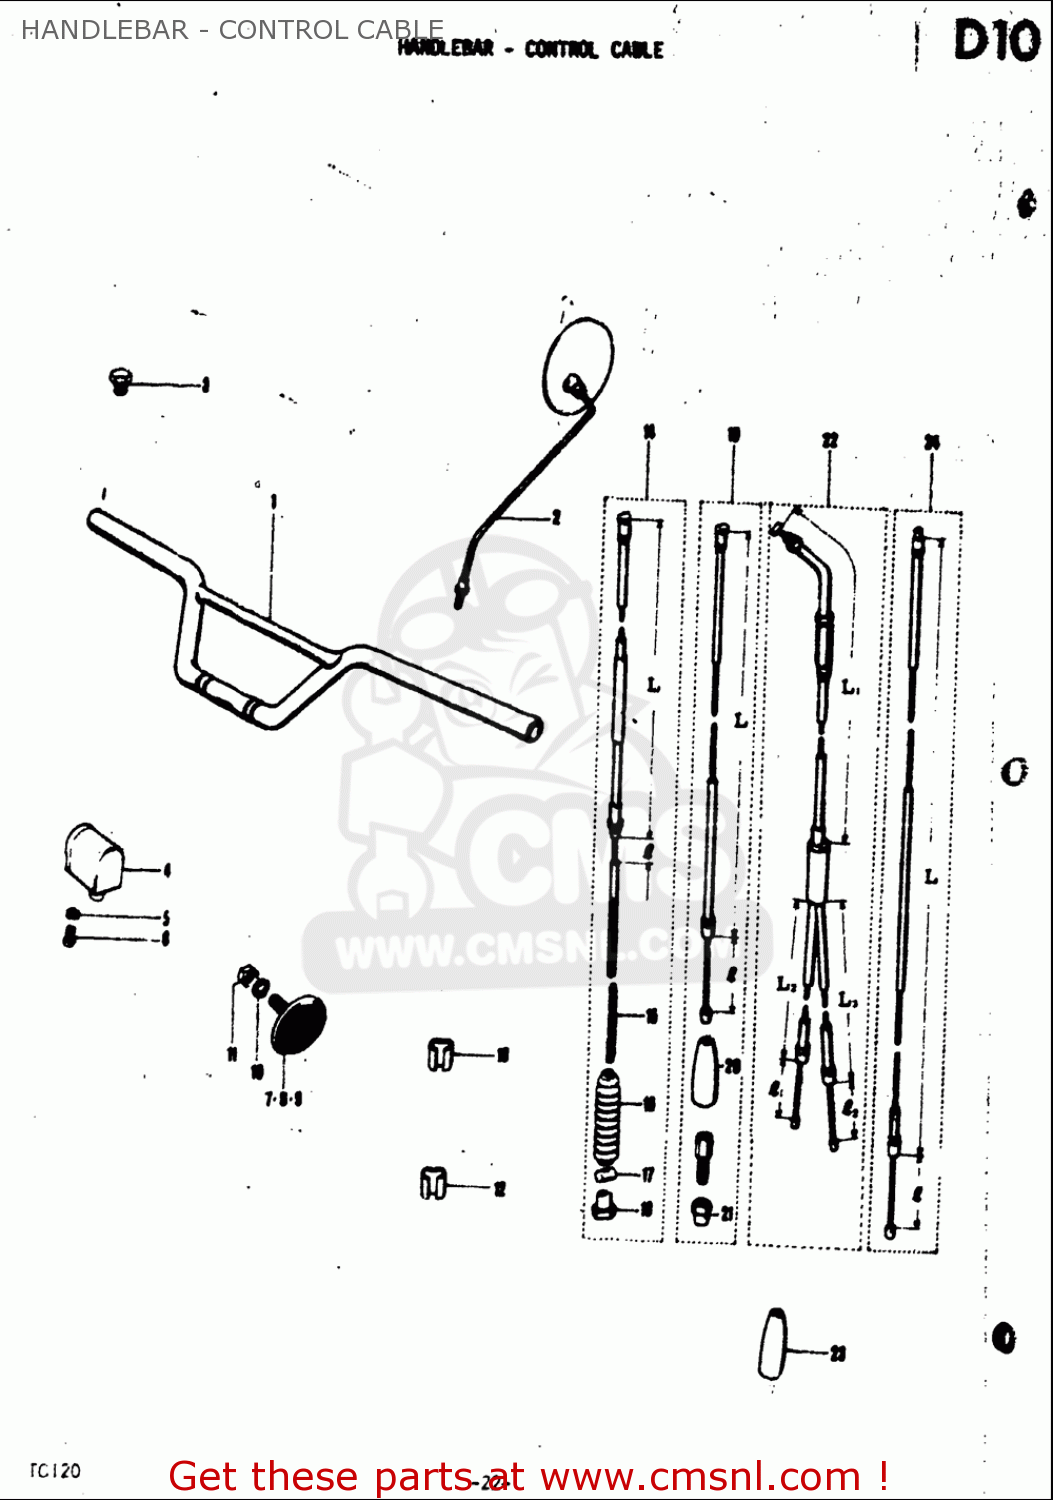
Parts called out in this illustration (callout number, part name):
1	HANDLEBAR
3	CAP
5	WASHER,LOCK
6	SCREW
10	WASHER,LOCK
11	NUT
12	CLIP
13	CLIP
15	SPRING
16	SEAL,DUST(7X16X75)
17	BRAKE ROD LEVER
18	BRAKE ROD ADJ N
19	CABLE ASSY,CLUTCH
21	NUT
22	CABLE ASSEMBLY,THROTTLE
